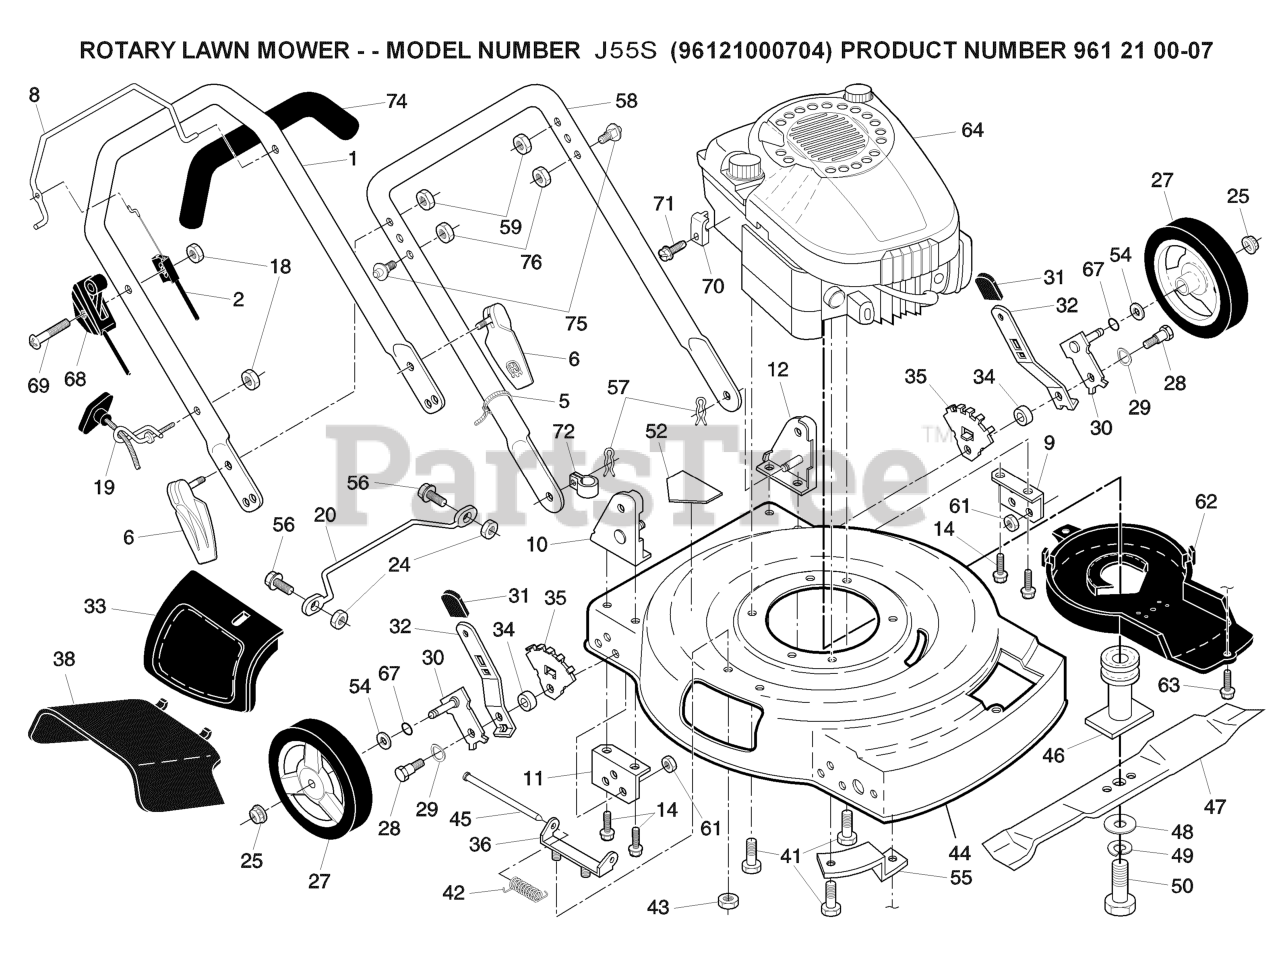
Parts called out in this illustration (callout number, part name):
2	ENGINE ZONE CONTROL CABLE
5	TIE GUIDE
6	ASM.QUICK.RELEASE
8	BAIL.COMF.FWGD.668.ORANGE.WALK
9	GUARD.SLKSCR.BELT.
10	HANDLE BRACKET ASM. RH
11	Support Bracket, Handle, RH
12	HANDLE BRACKET ASM. LH
14	SCREW.5/16-18X3/4
18	NUT
19	RB GUIDE.ROPE.STD.BLK.ZIN WSL
25	NUT.HEX.FLANGE.3/8-16.LO(3 2)
27	WHEEL & TIRES ASSY, FRONT
28	BOLT
29	WASHER.CURVED.CYLINDRICAL
30	AXLE ARM ASSY.
31	SELECTOR KNOB
32	SPRING.SEL.EXT.21.DOMED.12/14
33	DOOR.MULCH.22.EZ.MULCH.GREY
34	SPACER.HEIGHT.ADJUSTER
35	BRACKET.ADJ.WHEEL.5POS.ADS
36	BRACKET.ASM.HOUSING.EZ.MUL
38	DEFLECTOR.GUARD.22..EZ.MULCH
41	BOLT 3/8-16X1-1/8
42	TORSION SPRING
43	LOCKNUT.NYLOC.1/4-20
44	Kit, Mower Housing
45	ROD.HINGE.COMBI-C
46	BLADE ADAPTOR / PULLEY
47	Blade, 22"
48	WASHER,HARDEN
49	LOCKWASHER
50	SCREW, HEX HD 3/8-24 X 1-3/8
52	DECAL.INTERNATIONL.CUTFINGER
54	WASHER.FLAT.1/2
55	BRACKET
56	REPL BY 817 02 10-08
57	HAIRPIN COTTER
59	NUT.HEX.FLANGE.1/4
61	LOCKNUT PM
62	DEBRIS SHIELD
63	SCREW.HEX.WSH
67	O-RING..070X.487.NEOPRENE
68	THROTTLE CONTROL
70	CABLE CLAMP(ENGINE)
71	SCREW.HEX.HEAD.WASHER.10-16
72	CLIP.CABLE.BLK
74	GRIP.HANDLE.FOAM
75	STUD.QUICK.ADJUST
76	NUT.LOCK.5/16-18
